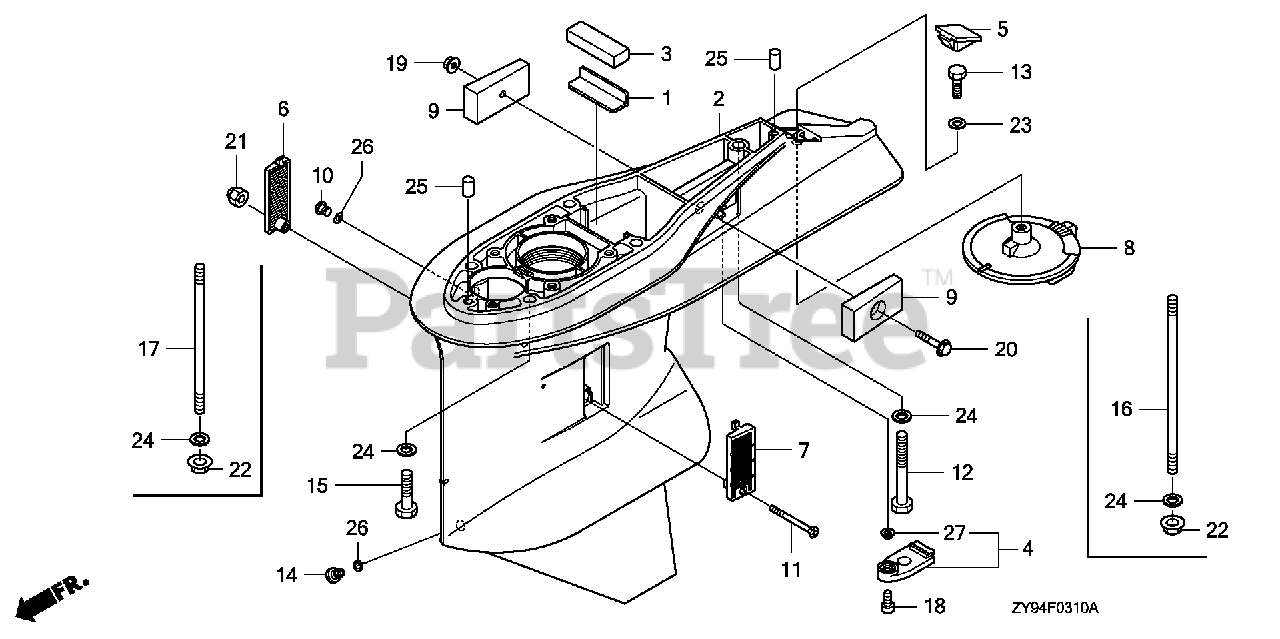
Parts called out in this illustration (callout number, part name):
1	PLATE, RUBBER SETTING
2	CASE, GEAR *NH282MU* (OYSTER SILVER METALLIC-U)
3	GROMMET, GEAR CASE
4	COVER B, GEAR CASE
5	GROMMET, GEAR CASE
6	SCREEN, R. WATER
7	SCREEN, L. WATER
8	TAB, TRIM *NH282MU* (OYSTER SILVER METALLIC-U)
9	METAL, ANODE
10	BOLT, OIL CHECK
11	SCREW, FLAT (5X55)
13	BOLT, HEX. (8X25)
14	BOLT, DRAIN PLUG
16	BOLT, STUD (10X202)
17	BOLT, STUD (10X164)
18	BOLT, SOCKET (6X16)
19	NUT, SELF-LOCK (6MM)
20	BOLT, FLANGE (6X35)
21	NUT, SELF-LOCK (5MM)
22	NUT, SELF-LOCK (10MM)
23	WASHER, PLAIN (8MM)
24	WASHER, PLAIN (10MM)
25	PIN, DOWEL (6X10)
26	O-RING (6.9X1.45)
27	COLLAR, DISTANCE (6.5X9X3)
